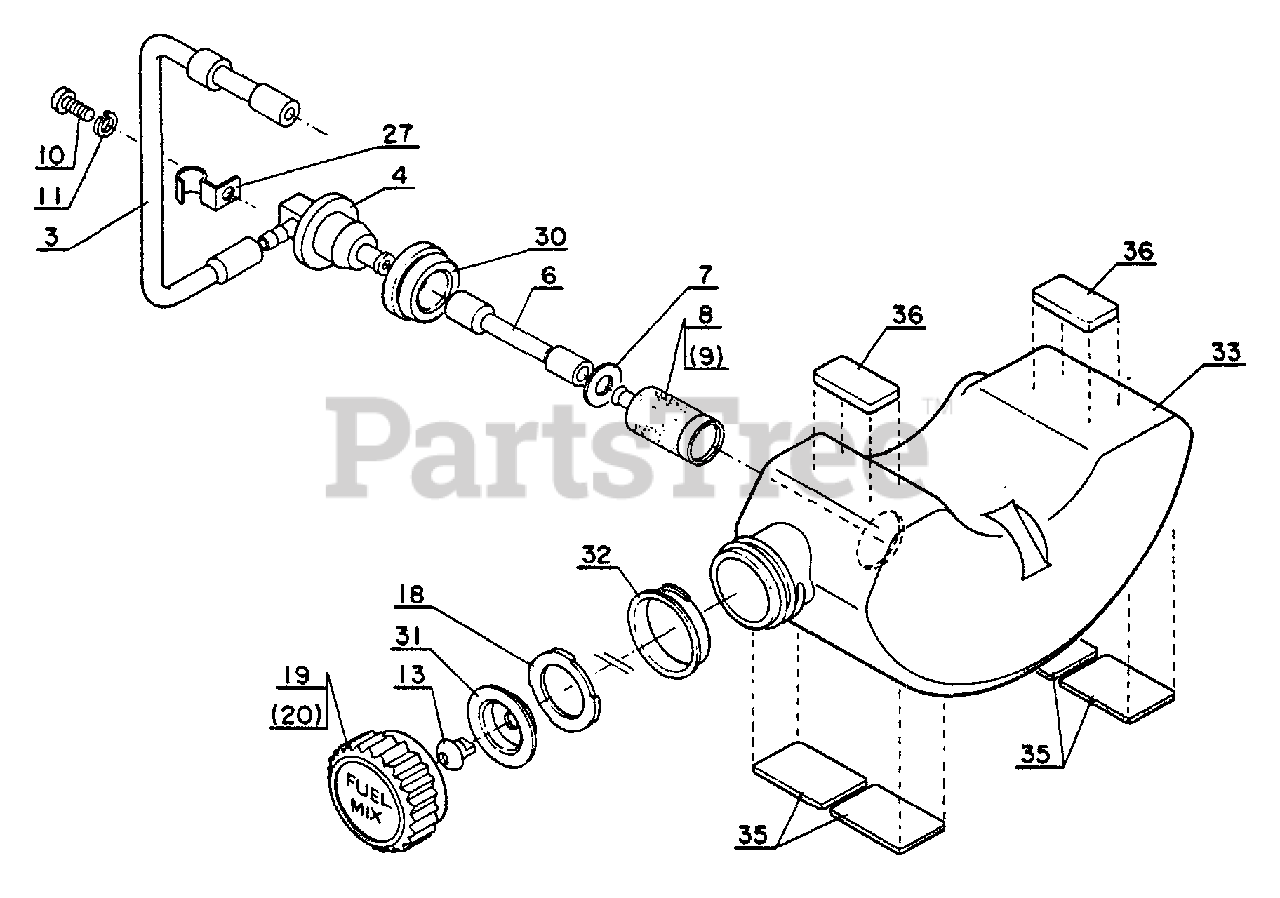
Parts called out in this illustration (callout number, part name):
3	PIPE, FUEL - OUTER
4	CONNECTOR, PIPE
6	PIPE, FUEL - INNER
7	WASHER 6.5×11.5×0.8
8	FILTER, FUEL
10	SCREW 4×12
11	WASHER, SPRING 4 MM
13	VALVE, CHECK
18	GASKET, CAP
19	CAP
27	CLAMP
30	CONNECTOR
31	HOLDER, CHECK VALVE
32	GASKET
33	TANK, FUEL
35	RUBBER SEAT (A)
36	RUBBER SEAT (B)
